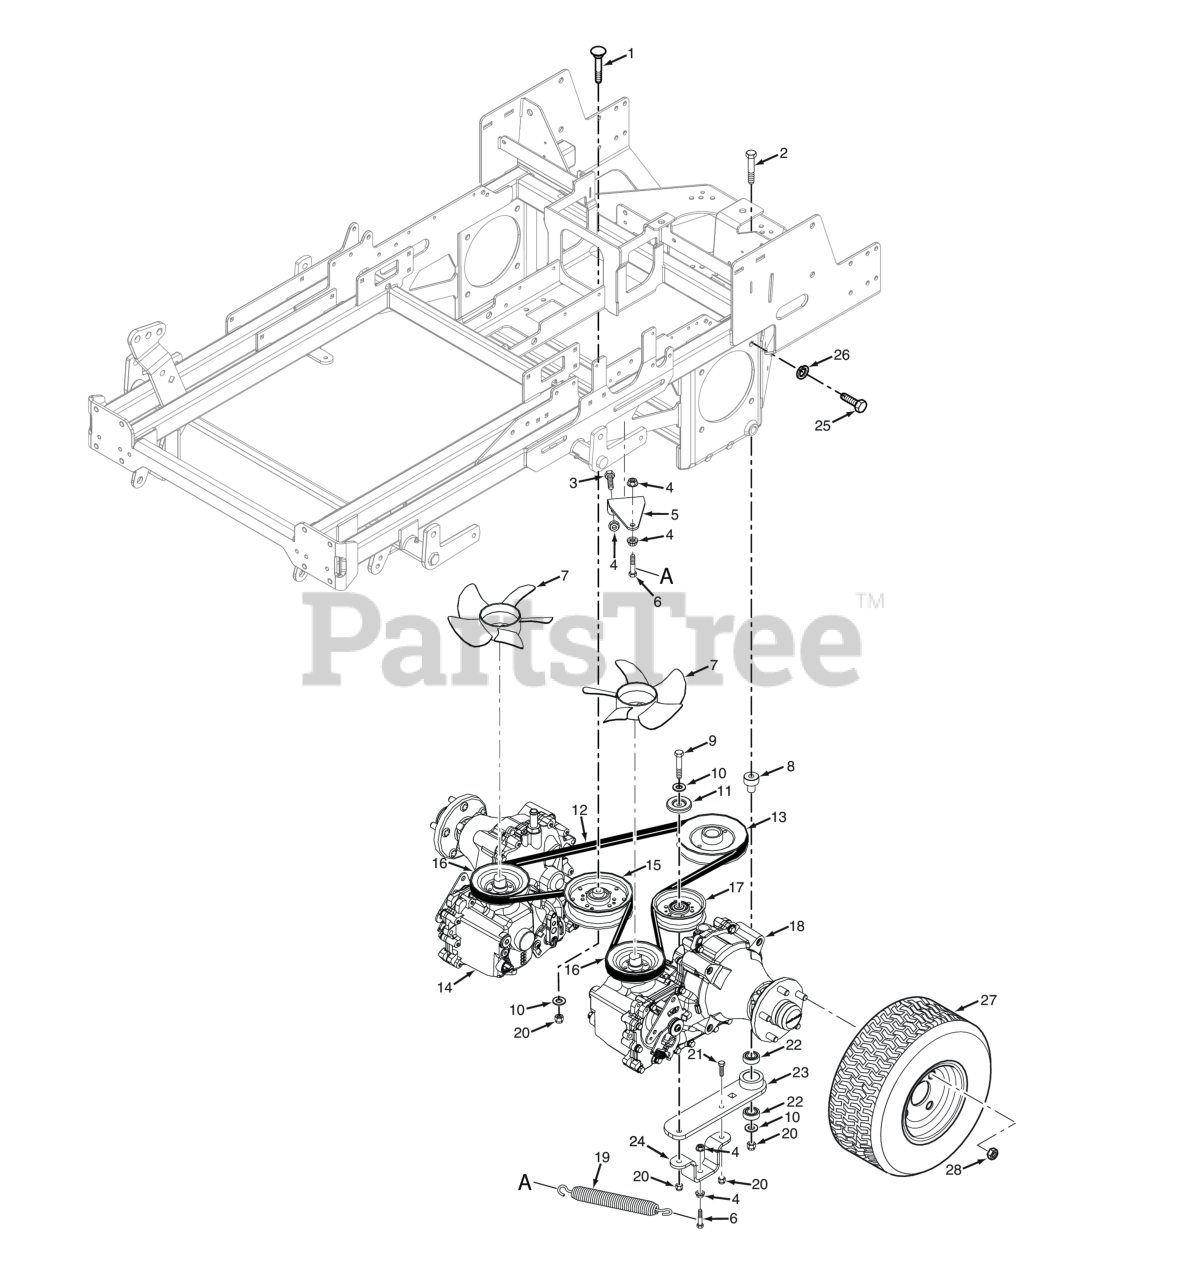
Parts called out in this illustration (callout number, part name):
1	Carriage Bolt, 3/8-16 x 2-1/2"
2	Bolt, Hex Head 3/8-16 x 3" - 52"
3	Bolt, Hex Head, 3/8-16 x 1 Gr. 5
4	NUT, 3/8-16 SERRATED FLANGE HEX HEAD
5	Mounting Bracket, Spring - Idler Arm
6	Bolt, Hex Head 3/8-16 x 1-1/2" Grade 8 Black
7	Kit, Fan / Pulley
8	Pivot, Idler Long - 52"
9	Capscrew, Hex Head 3/8-16 x 2.75"
10	Flatwasher, 3/8 (.391 x .938 x .105 HD) Grade 8
11	Quick Pin, 5/16" Dia.
12	Belt, Pump Drive STT
13	Pulley, 5.80" Dia. - 1.125 Bore
14	Transaxle, RH
15	Idler Pulley, Belt Clutch
16	Kit, Fan / Pulley
17	Pulley, 4" Dia. Idler
18	Transaxle, LH
19	Spring, Pump Drive
20	HEX NUT, ELASTIC STOP LOCK, 3/8-16
21	Bolt, Hex Head 3/8-16 x 1-1/4", Kawasaki FX / FS
22	BEARINGS, BALL, NEUTRAL RETURN
23	Idler Arm Assembly
24	Mounting Bracket, Idler
25	Bolt, Hex Head 1/2-13 x 1-1/4"
26	Lockwasher, 1/2" Spring
27	Wheel Assembly, 24 x 12-12 4-Ply (5-Hole)
27	Rim w/Valve Stem
27	Tire, 24 x 12-12 Turf Master
28	Wheel Nut, 1/2-20 x 13/16
